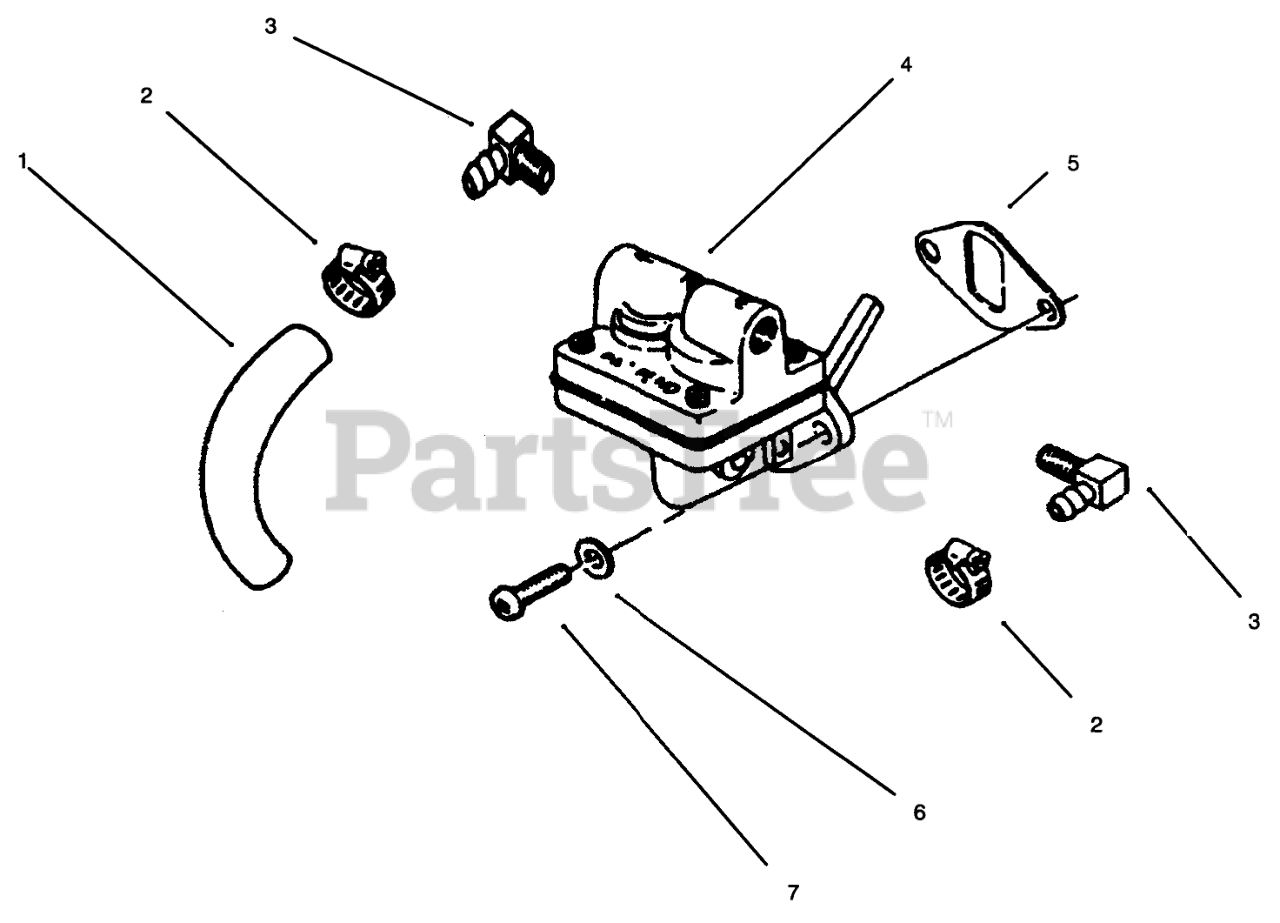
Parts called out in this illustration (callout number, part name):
1	Line-Fuel
2	Clamp
3	Connector-90deg.
4	Pump ASM-Fuel INC 5&7
5	Gasket
6	Washer
7	Screw-F.H.
